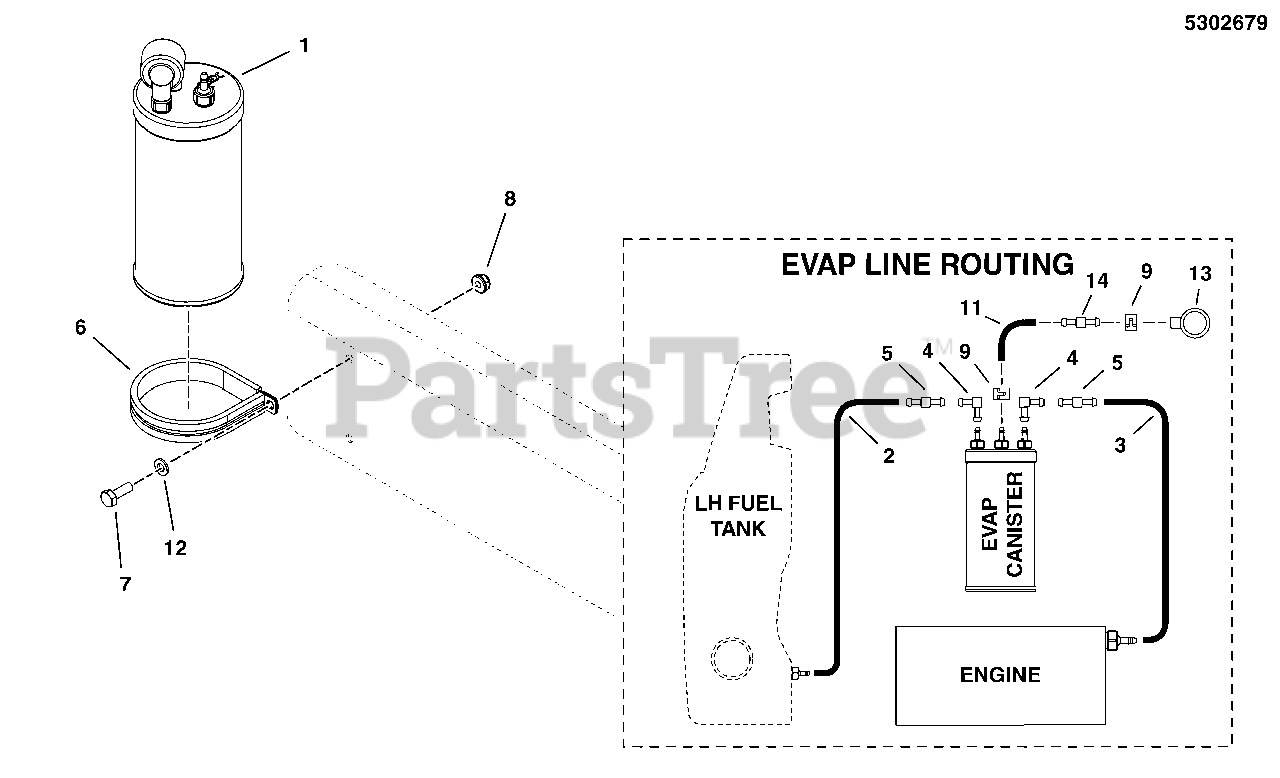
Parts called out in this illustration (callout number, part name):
1	CNSTR, CARB, 6 GAL
2	HOSE, VAPOR, 5MM ID, 26.00 LG
3	HOSE, VAPOR, 5MM ID, 11.50 LG
4	FITTING, 90 DEG, 3/16X3/16, SANTOPRENE
5	FITTING, STRAIGHT, 3/16X3/16, PLASTIC
6	CLAMP, 3" ID, CUSHIONED, STAINLESS
7	BOLT, 1/4-20 X 3/4, ALLEN BUTTON HD, YZ
8	NUT, 1/4-20 HEX NYLOCK FLANGE (5025391)
9	CLAMP, HOSE
10	DECAL, EPA CERT, ZTRS
11	HOSE, FORMED, EVAP CANISTER
12	WASHER, 1/4 SAE (5025154)
13	DUST FILTER, CANISTER
14	FITTING, STRAIGHT, 10MMX10MM, PLASTIC
